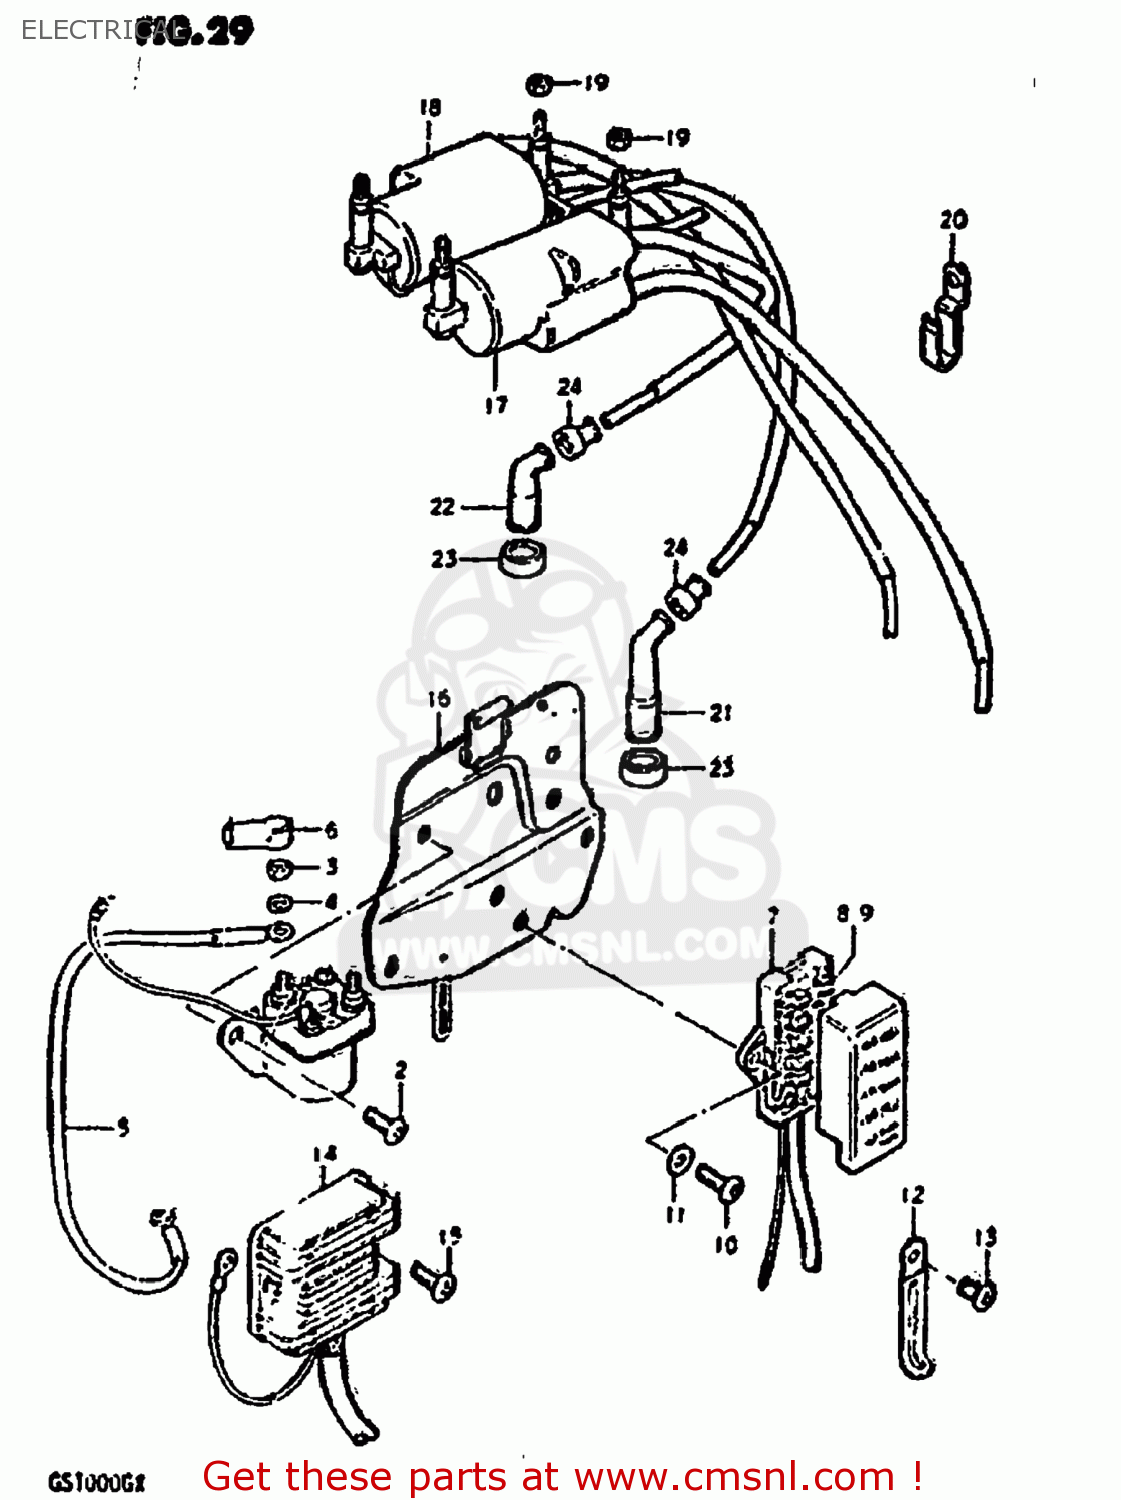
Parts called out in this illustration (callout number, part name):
1	RELAY ASSY,STARTING MOTOR
2	SCREW
3	NUT 6MM
4	LOCK WASHER
5	WIRE,STARTER MOTOR LEAD
6	CAP,STARTER RELAY
7	BOX ASSEMBLY,FUSE
8	FUSE(10A)
9	FUSE(15A)
10	SCREW 6X12
11	WASHER
12	CLAMP L:35
13	SCREW
14	RECTIFIER ASSEMBLY
15	SCREW 6X12
16	HOLDER COMP,ELECTRONIC PARTS
17	COIL ASSEMBLY,IGNITION
18	COIL ASSEMBLY,IGNITION
19	NUT
20	CLAMP
21	CAP ASSY,SPARK PLUG
22	CAP,SPARK PLUG
23	SEAL,SPARK PLUG
24	SEAL,SPARK PLU
